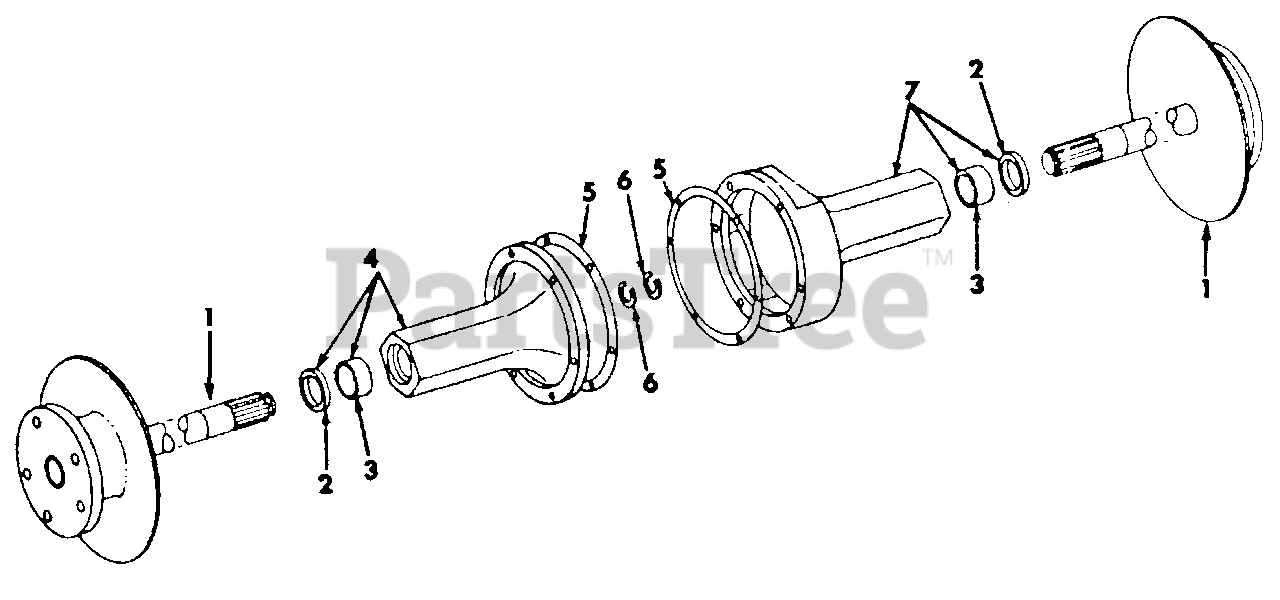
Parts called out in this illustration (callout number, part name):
1	Axle Assy, Rear
2	Seal, Oil
3	Bearing, Needle
4	Carrier Assy, Rear Axle, LH
5	Gasket, Carrier
6	Ring, Retaining
7	Carrier Assy, Rear Axle, RH
